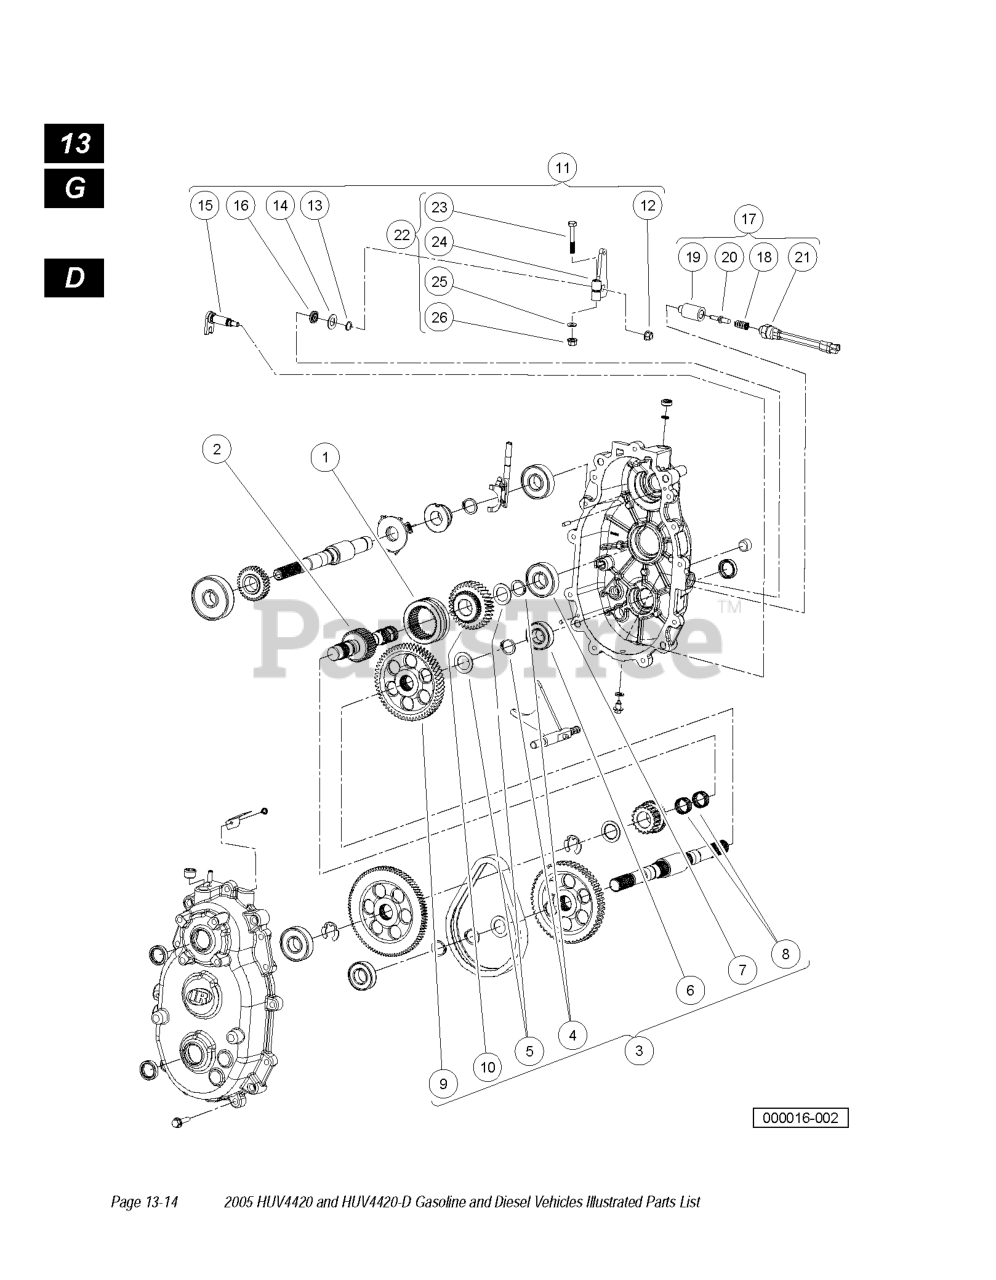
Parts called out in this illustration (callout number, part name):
1	DOG, ENGAGEMENT
2	SHAFT, INTERMEDIATE
3	KIT-FORWARD GEAR REPAIR
4	RING, RETAINING, BASIC EXTERNA
5	WASHER, THRUST, 1.007 X .062
6	BEARING, BALL, 6205 C3
7	BEARING, BALL, 6305 C3
8	BEARING, NEEDLE, SPLIT CAGE
11	KIT- TRANS SHIFT SHAFT REAPAIR
12	NUT, LOCK HEX, NYLON, 5/16-24
13	RING, RETAINING, EXTERNAL 9/16
14	WASHER, FLAT, .58 X 1.08 X .05
17	KIT-NEUTRAL SWITCH REPAIR
22	KIT, BELLCRANK, D SHAPE, CLAMP
23	BOLT, 3/8-16 X 2.00 HEX HEAD
24	ASM, BELLCRANK, D SHAPE, CLAMP
25	WASHER, 3/8 FLAT
26	LOCKNUT, 3/8-16 HEX
